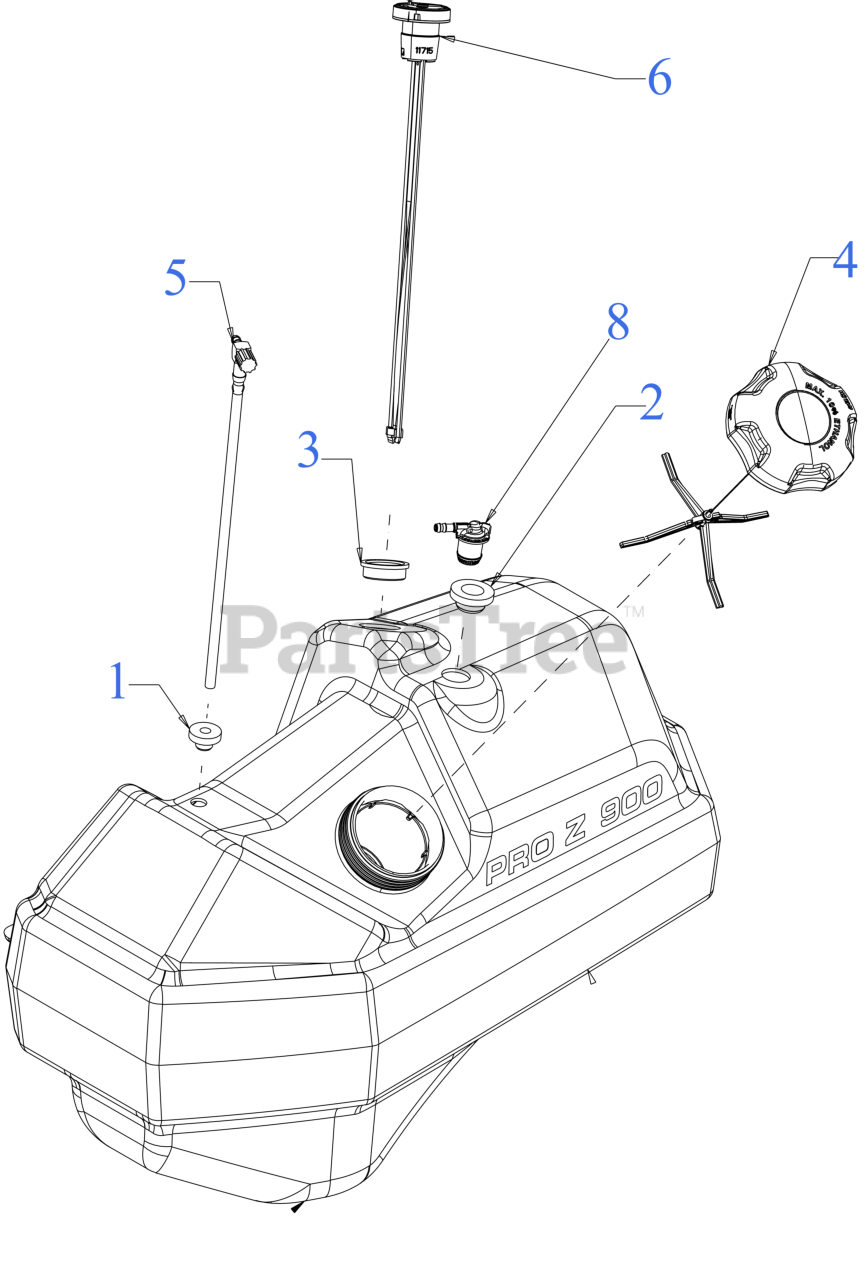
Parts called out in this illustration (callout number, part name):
1	GROMMET-FUEL TANK
2	GROMMET .755 x .955 x .55
3	GROMMET 1.174X1.400X0.505
4	FUEL CAP - 3.50" ONE WAY VENT
5	FUEL PICKUP VALVE
6	FUEL GAUGE
8	FUEL VENT FITTING
